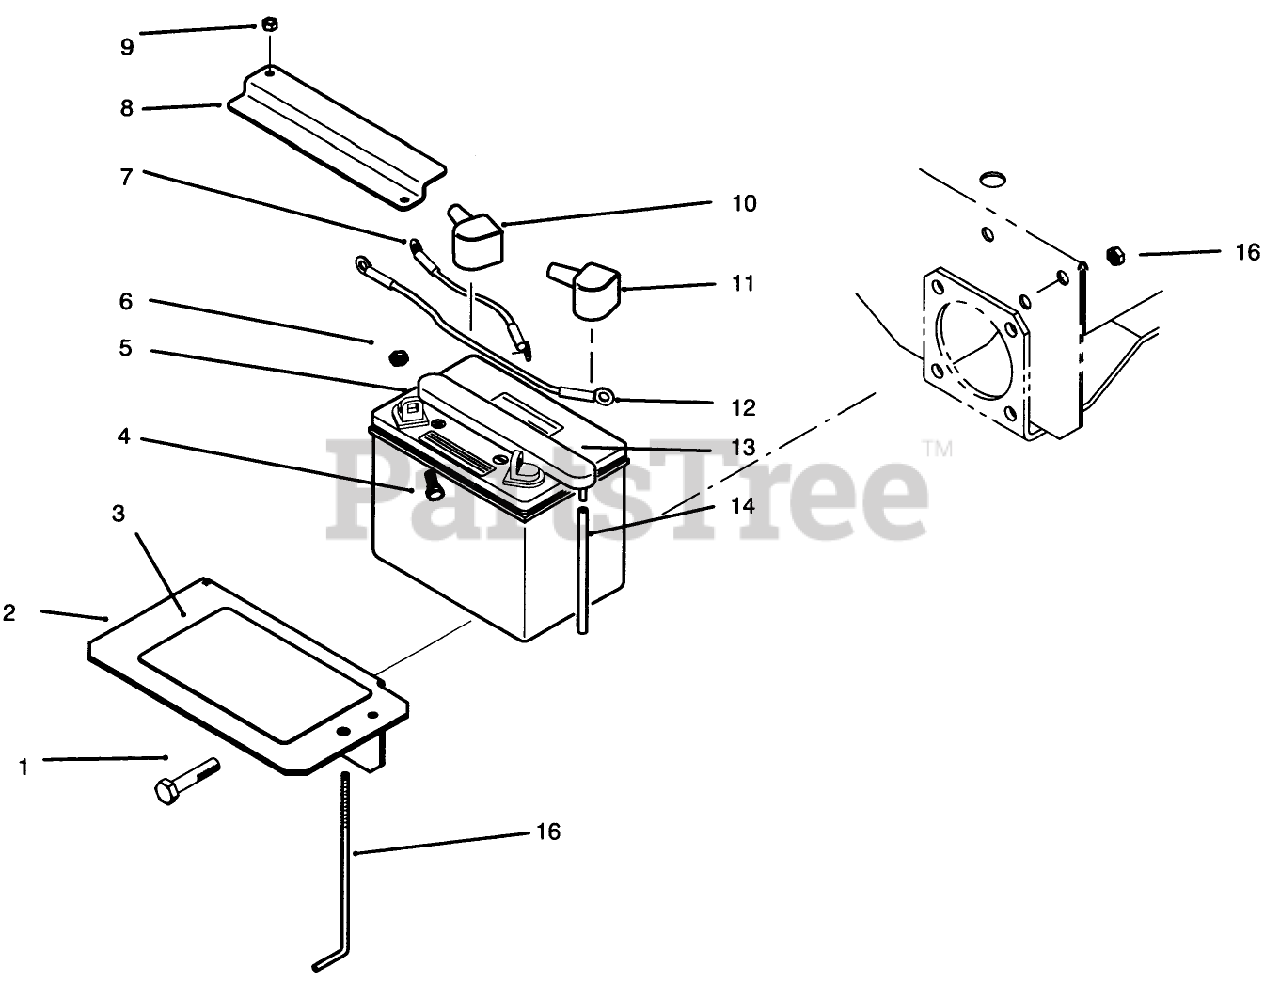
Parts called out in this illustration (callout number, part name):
1	SCREW-HH
3	PAD-SKID, ANTI
4	SCREW-HH
6	NUT-KEPS
7	WIRE ASM
10	BOOT-TERMINAL, BLACK
11	BOOT-TERMINAL, RED
11	NUT-LOCK, NI
12	WIRE-SOLENOID/STARTER
14	TUBE-VENT
15	NUT-LOCK, NI
16	ROD-SUPPORT, BATTERY
